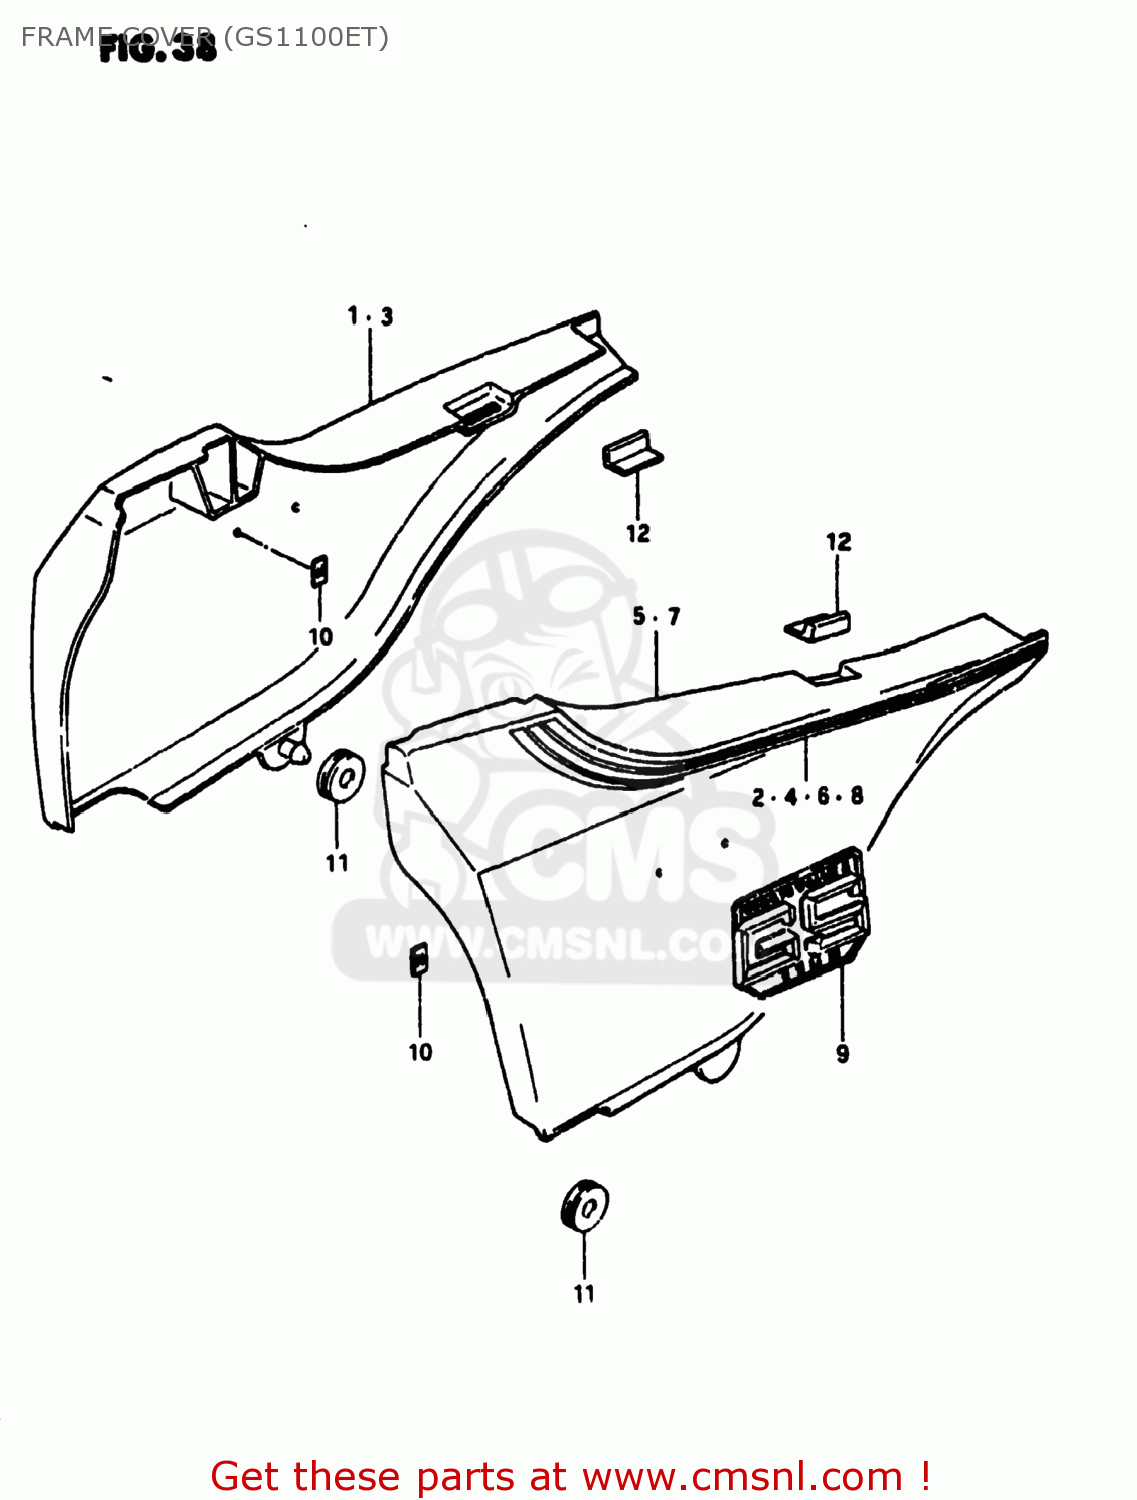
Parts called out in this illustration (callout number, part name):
1	COVER,FRAME,R
3	COVER,FRAME,R
5	COVER,FRAME,L
6	TAPE,FRAME COVER
7	COVER,FRAME,L
8	TAPE,FRAME COVER
9	EMBLEM,FRAME COVER
10	NUT
11	CUSHION
12	CUSHION,FRAME COVER
